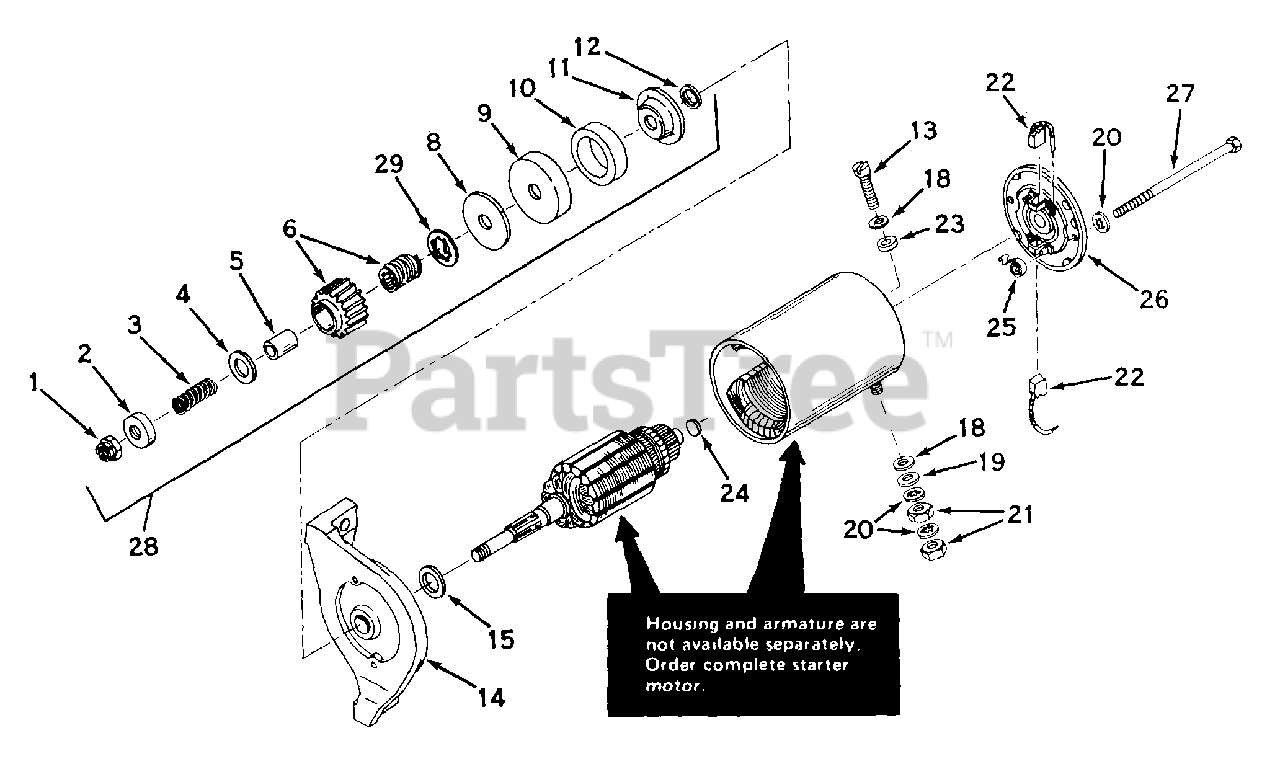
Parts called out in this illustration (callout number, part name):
1	"Nut, Hex
2	Stop, Pinion
3	Spring, Anti-drift
4	Washer, Pinion
5	Sleeve, Anti-drift
6	Gear & Screw Shaft Assembly
8	Washer, Thrust
9	Cup, Cushion
10	Cushion, Rubber
11	Washer, Thrust
12	Bushing, Thrust
13	Bolt, Terminal
14	Cap Assy., Drive end 5/8" Bore
15	Washer, Spacing (.039 thick)
15	Washer, Spacing (.008 thick)
18	Washer, Insulating
19	Washer, Plain
20	Washer, Lock
21	Nut, Hex
22	Brush & Spring Kit
23	Bushing, Insulating
24	Washer, Spacing
25	Spring, Brush
26	End Cap Assy., Commutator
27	Bolt, Thru
28	Drive Assy., Complete
29	Stopper, Screw
